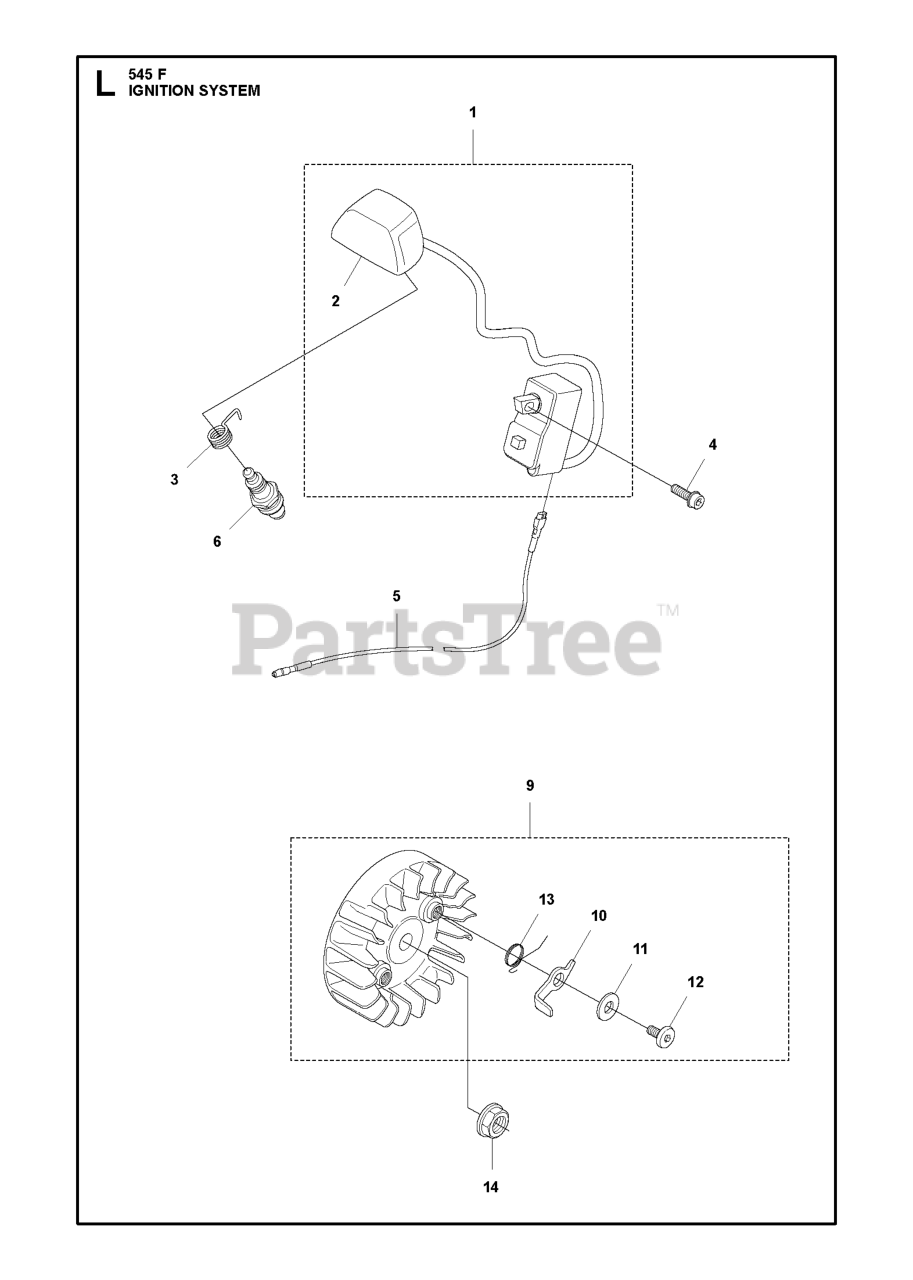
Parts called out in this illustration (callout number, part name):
1	IGNITION MODULE
2	SPARK PLUG CAP
3	CONTACT SPRING
4	SCREW IHSCFM
5	SHORT CIRCUIT CABLE
6	CMR6H SPARK PLUG NGK
10	STARTER PAWL
13	SPRING PAWL
14	NUT W/ WASHER
